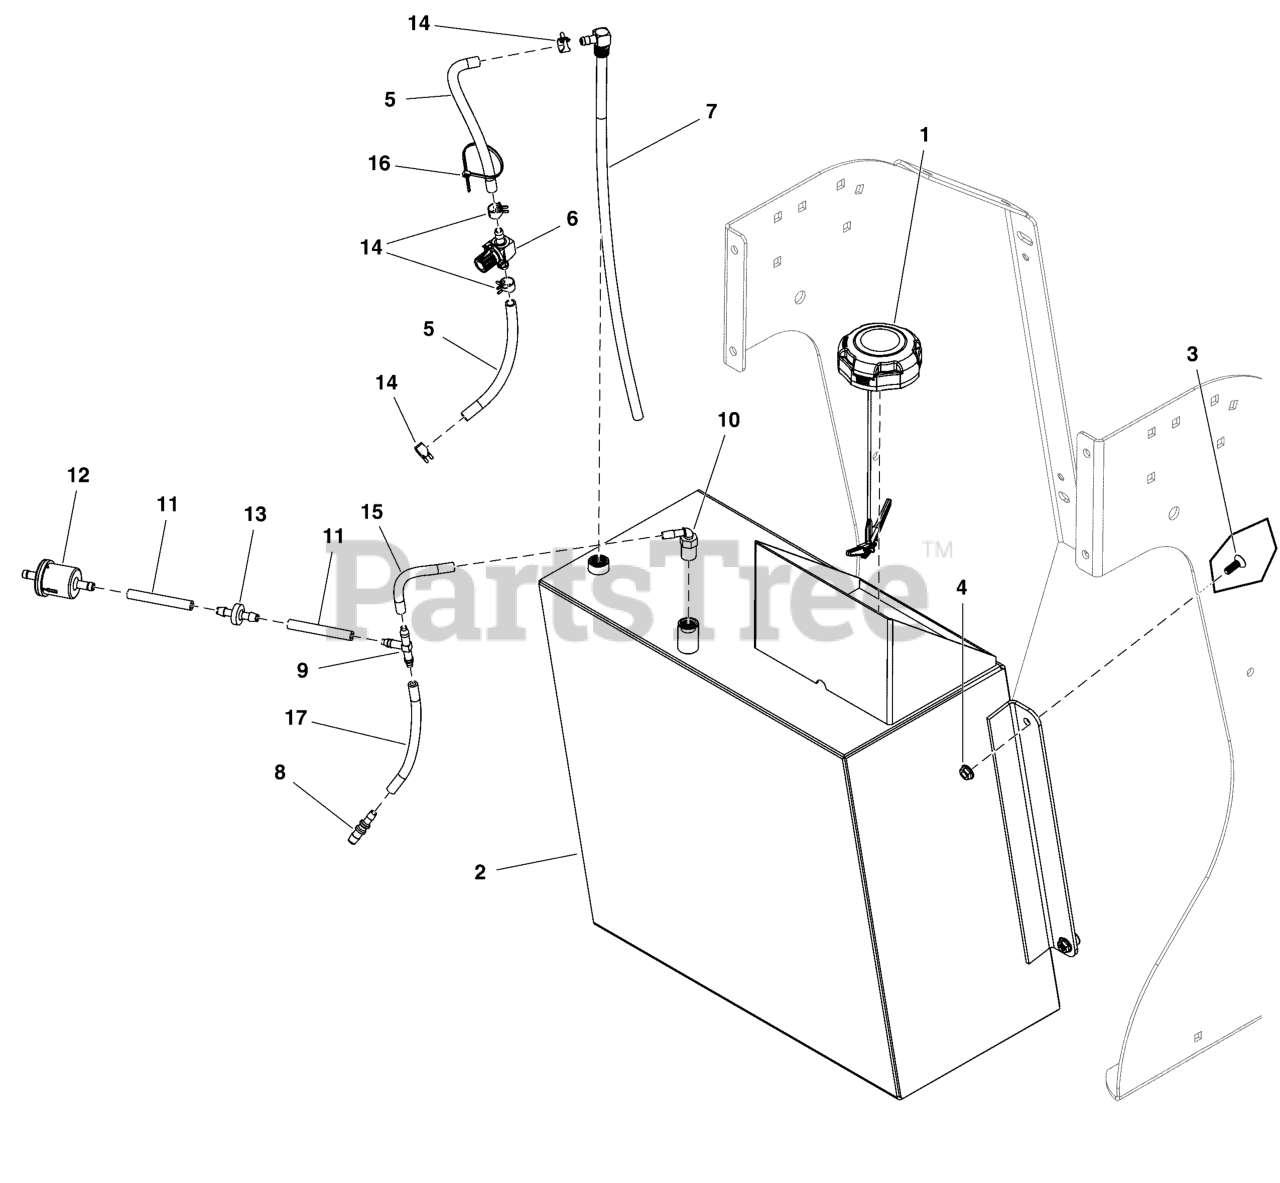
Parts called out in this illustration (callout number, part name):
1	FUEL CAP, 2.0, NON VENTED
2	WELD, FUEL TANK, BLOWER
2	ASSM, FUEL TANK, BLOWER
3	SCREW, 1/4-20 X 3/4, FPHMS, SS
4	NUT, 1/4-20 HEX SERR. FLANGE
5	HOSE, 1/4" FUEL, 6" LONG
6	VALVE, FUEL SHUT OFF
7	PICKUP TUBE ASM,FUEL 16.75
8	FITTING, 1/4X3/16 REDUCER
9	FITTING, 1/4 TEE,BARB TYPE
10	FITTING, 90, 1/4-18 NPT NYLON
11	HOSE, VAPOR, 5MM ID, 2.50 LG
12	FILTER, FUEL
13	CHECK VALVE ASMY
14	HOSE, VAPOR, 5MM ID, 4.00 LG
15	CLAMP, Hose
16	TIE, SELF-LOCKING, 6"
17	HOSE, Vapor, 5 MM ID, 6.00 LG
